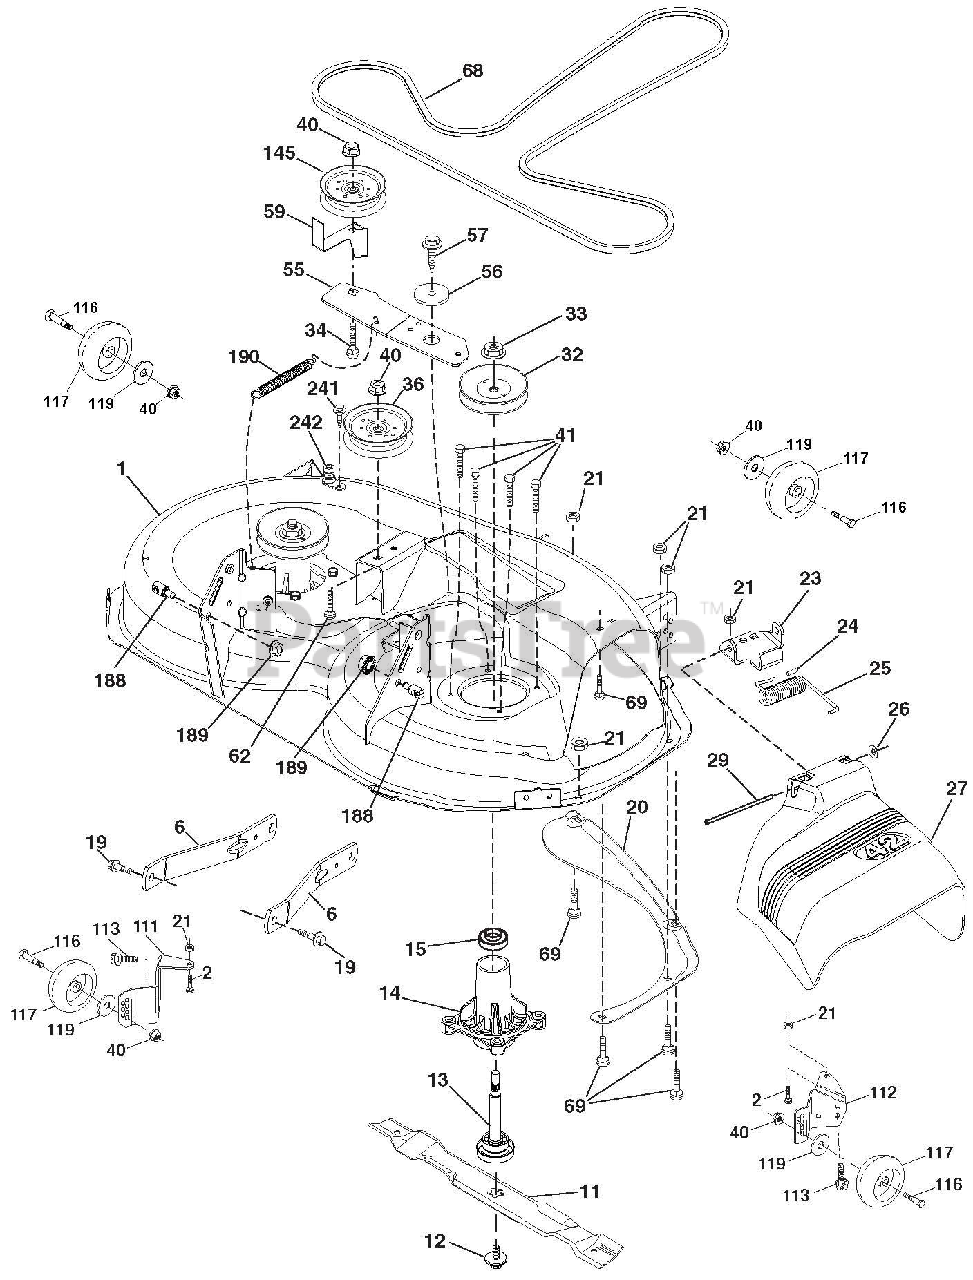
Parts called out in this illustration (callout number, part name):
1	MOWER HOUSING
6	ARM.SUSPENSION.MOWER.REAR.LD
11	BLADE.MOWER.42"HI LIFT PREMIUM
12	SCREW 7/16-20 X 1
13	SHAFT ASM
14	HOUSING.MANDREL.4PT.SERVICE
15	BEARING
19	BOLT.SHOULDER
20	BAFFLE.VORTEX.42.STD/HEAVY DTY
21	Nut, Hex, Crownlock 5/16-18
23	BRACKET.DEFLECTOR.38/42"2005
24	CAP.SLEEVE..80X.112.BLK.MOWER
25	SPRING.TORSION.DFL.38/42/46.GR
26	NUT.PUSH.PHOS.& OIL
27	SHIELD.DEFLECTOR.
29	ROD.HINGE.42/46"
32	MANDREL.PULLEYS.42,44,50
32	MANDREL ASM
33	NUT.FLANGE.LOCK.TOP
34	BOLT.CARR.SH.3/8-16X1-1/2.GR5
36	PULLEY.IDLER.4.50.RAW
40	Nut, Hex, Flangelock 3/8-16
41	HEX HEAD BOLT
55	IDLER.ARM
56	SPACER.RETAINER
57	SCREW.3/8-16X1.SMGML.TAP/R.BLK
59	GUARD.TUV.IDLER
62	BOLT.RD.HD.SQ.NK.3/8-16UNC X 2
68	V-Belt, 42" Mower
69	BOLT.RDHD.SQNK.5/16-18 X 5/8
111	BRACKET WHEEL GAUGE LH
112	BRACKET WHEEL GAUGE RH
113	BOLT.5/16-18HEX.WHS.HD.LCKSERR
116	BOLD SHLD "A" 2.41 "B" 1.66
117	WHEEL.GAGE.HALF.SPOKED
119	Washer 3/8 x 7/8 x 14 Ga.
145	PULLEY.IDLER 48"PRIMARY
188	STUD.FASTNER.W/'D'ANTI-ROTATIO
189	Nut, Lock Hex Flange 5/16-18 u
242	PORT WASHOUT
